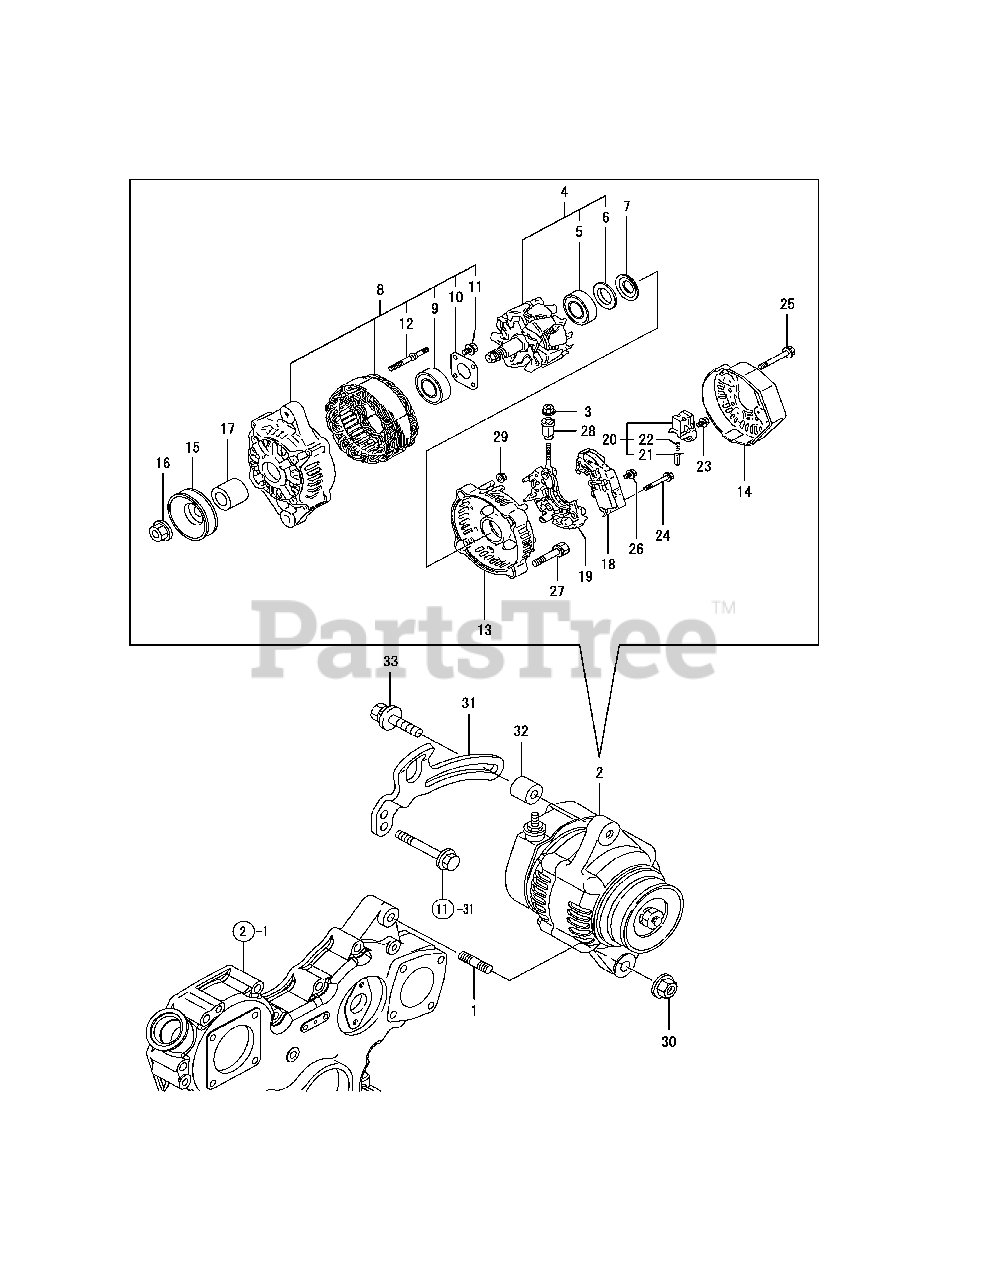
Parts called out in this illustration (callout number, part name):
6	COVER, BEARING
8	FLAME ASSY, DRIVE
13	FLAME ASSY, REAR
18	REGULATOR ASSY
26	SCREW W/WASHER
28	INSULATION BUSH
31	ADJUSTER, BELT
33	BOLT, ADJUSTING
